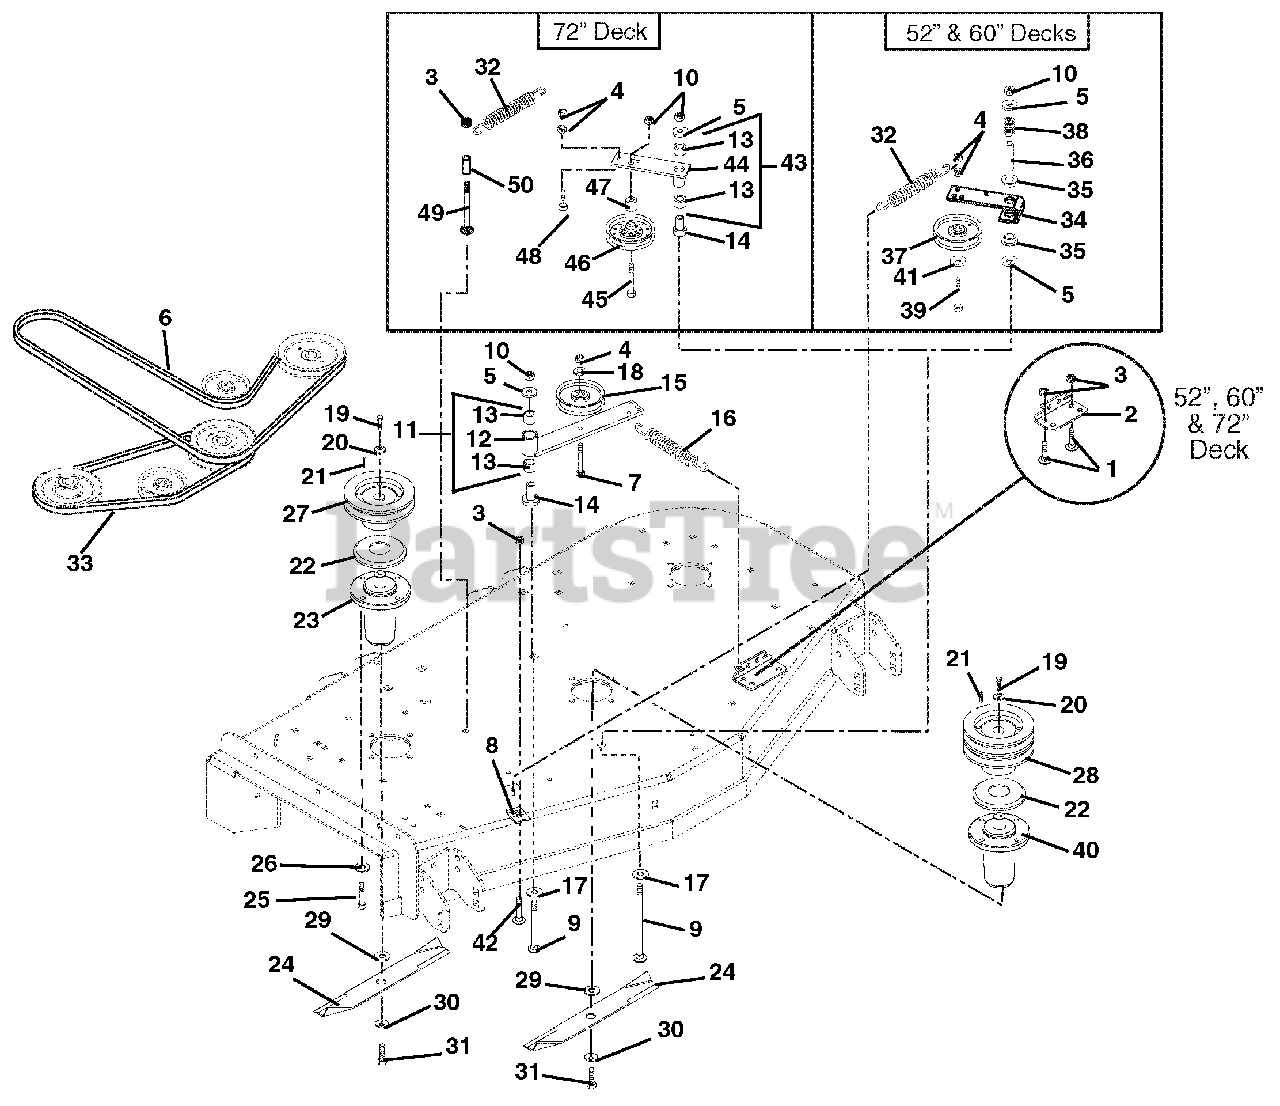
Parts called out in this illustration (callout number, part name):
1	Bolt, Round Head Square Neck .38-16 x .75 Grade 5
2	Bracket, Spring
3	Nut, Locking Top Flange .38-16 (045, 046, 047, 048, 052)
4	Nut, Locking Center .38-16
5	Washer, Flat Steel .531 x 1.25 x .10 (045, 046, 047, 048, 052)
6	V-Belt, B-Section 54.06 x .625 (045, 052)
7	Bolt-Round Head Square Neck .38-16 x 2.75 Grade 5
8	Anchor, Spring
9	Bolt, Round Head Square Neck .50-13 x 3.50 Grade 5
10	Nut, Locking Top Flange .50-13 (045, 046, 047, 048, 052)
11	Assembly, Idler Pivot Arm (Contains Items 12 & 13)
12	Weldment, Idler Pivot Arm
13	Bearing, 1.00 x 1.12 x .75
14	Bearing, Pedestal Powdered Metal (045, 046, 047, 048, 052)
15	Idler, Flat 4.00 x .38 (2.00 W)
16	Spring, Extension .09 x 1.00 x 6.00
17	Washer, Flat Steel .755 x 1.375 x .062
18	Washer, Flat Steel .375 x 1.125 x .065
19	Bolt, Hex .38-16 x 1.00 Grade 8
20	Washer, Cupped Serrated .375
21	Key, Square .25 x .25 x 1.00
22	Slinger, Dust
23	Assembly, Maintenance Free Spindle
24	Blade, Mower (049, 053)
25	Bolt, Hex .38-16 x 1.00 Grade 5
26	Washer, Locking .38 x .094 Regular
27	Weldment, Spindle Sheave 5.00 (045, 052)
28	Sheave, Double (5.25) (045, 052)
29	Washer, Flat .64 x 1.81 x .25
30	Washer, Bellville .63 x 1.625 x .14
31	Bolt, Hex .62-18 x 1.75 Grade 8
32	Spring, Extension
33	V-Belt 5L-Section 49.97 x .672 (049, 053)
34	Arm, Idler Pivot
35	Bushing, Flange .762 x 1.00 x .58 x 1.48 Nylon
36	Spacer .56 x .75 x 2.44 Steel
37	V-Idler, 4.00 x .38
38	Spring, Compression .085 x .80 x 1.00
39	Bolt, Hex .38-16 x 2.25 Grade 5
40	Spindle Assembly (Center)
41	Washer, Flat Steel .406 x .812 x .065
42	Bolt, Round Head Square Neck .38-16 x 1.00 Grade 5
43	Assembly, Idler Arm Guard Drive (Includes Items 13 and 44) (049, 053)
44	Weldment, Idler Arm Ground Drive (049, 053)
45	Bolt, Hex .38-16 x 6.00 Grade 5 (049, 053)
46	Idler, Flat Pulley 6.75 x .51 (049, 053)
47	Spacer .513 x .748 x .62 (049, 053)
48	Bolt, Hex .38-16 x 1.25 Grade 5 (049, 053)
49	Bolt, Round Head Square Neck .38-16 x 2.75 Grade 5 (049, 053)
50	Spacer .38 x .625 x 1.50 (049, 053)
